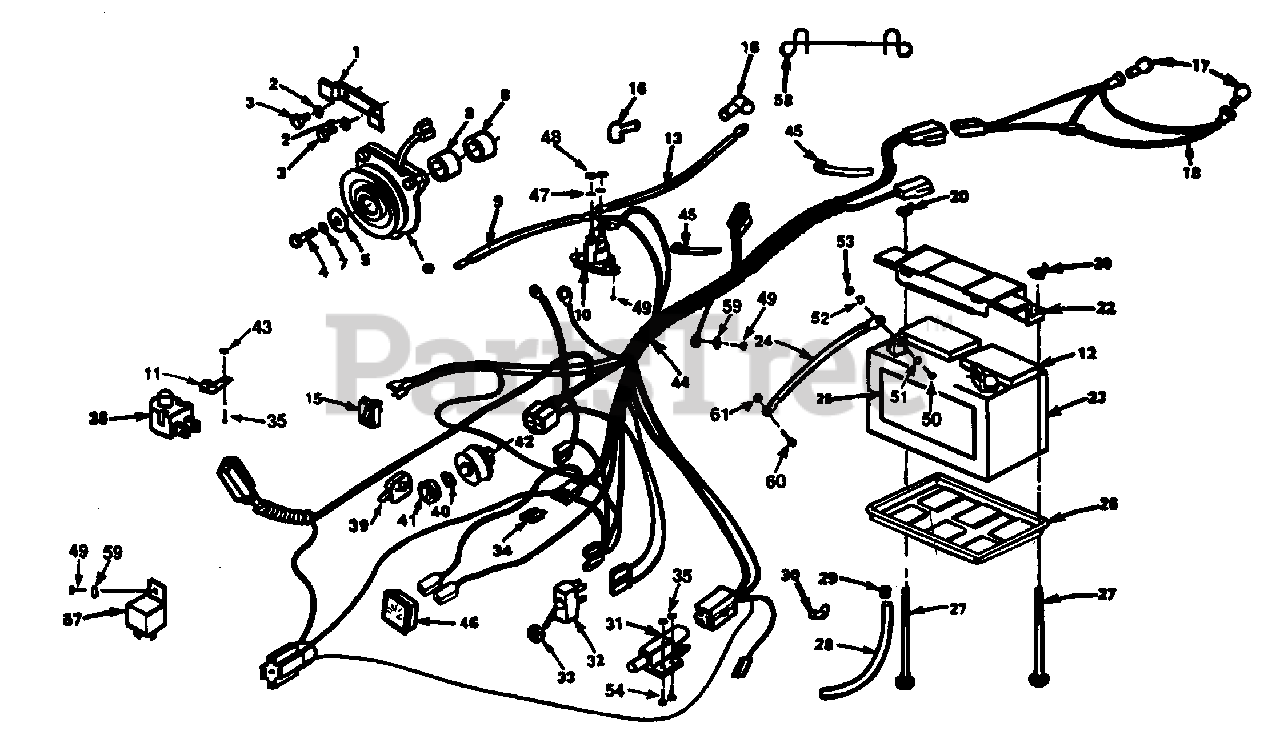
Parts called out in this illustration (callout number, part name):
1	Clutch Stop (AYP part number)
2	Lock Washer (AYP part number)
3	Hex Bolt (AYP part number)
4	Hex Bolt (AYP part number)
5	Washer (AYP part number)
6	Electric Clutch (AYP part number)
7	Lock Washer (AYP part number)
8	Clutch Spacer (AYP part number)
9	Battery Cable (AYP part number)
10	Solenoid (AYP part number)
11	Insulated Clip (AYP part number)
12	Battery Caps (AYP part number)
13	Starter Cable (AYP part number)
15	Light Switch (AYP part number)
16	Terminal Cover (AYP part number)
17	Light Bulb (AYP part number)
18	Light Socket Harness (AYP part number)
20	Wing Nut (AYP part number)
22	Terminal Guard (AYP part number)
23	Battery (AYP part number)
24	Ground Cable (AYP part number)
25	Battery Decal (AYP part number)
26	Battery Tray (AYP part number)
27	Carriage Bolt (AYP part number)
28	Plastic Tube (AYP part number)
29	Hose Clamp (AYP part number)
30	Clip (AYP part number)
31	Interlock Switch (AYP part number)
32	P.T.O. Switch (AYP part number)
33	Hex Nut (AYP part number)
34	30 Amp Fuse (AYP part number)
35	No. 10-32 Keps Nut (AYP part number)
38	Seat Switch (AYP part number)
39	Key (AYP part number)
40	Ignition Nut (AYP part number)
41	Ignition Bezel (AYP part number)
42	Ignition Switch (AYP part number)
43	Slot Pan Hd. Screw (AYP part number)
44	Ignition Harness
45	Tie Cable (AYP part number)
46	Ammeter (AYP part number)
47	Lock Washer (AYP part number)
48	Hex Jam Nut (AYP part number)
49	Thd. Cutting Washer Hd. Hex Screw (AYP part number)
50	Hex Bolt 1/4-20 x 3/4 (AYP part number)
51	Washer (AYP part number)
52	Lock Washer 1/4 (AYP part number)
53	Hex Nut 1/4-20 (AYP part number)
54	Washer Hd. Hex Screw (AYP part number)
57	Relay Assembly (AYP part number)
58	Wire Tie (AYP part number)
59	Ext. Tooth Lock Washer (AYP part number)
60	Crownlock Nut
61	Fin. Hex Bolt (AYP part number)
